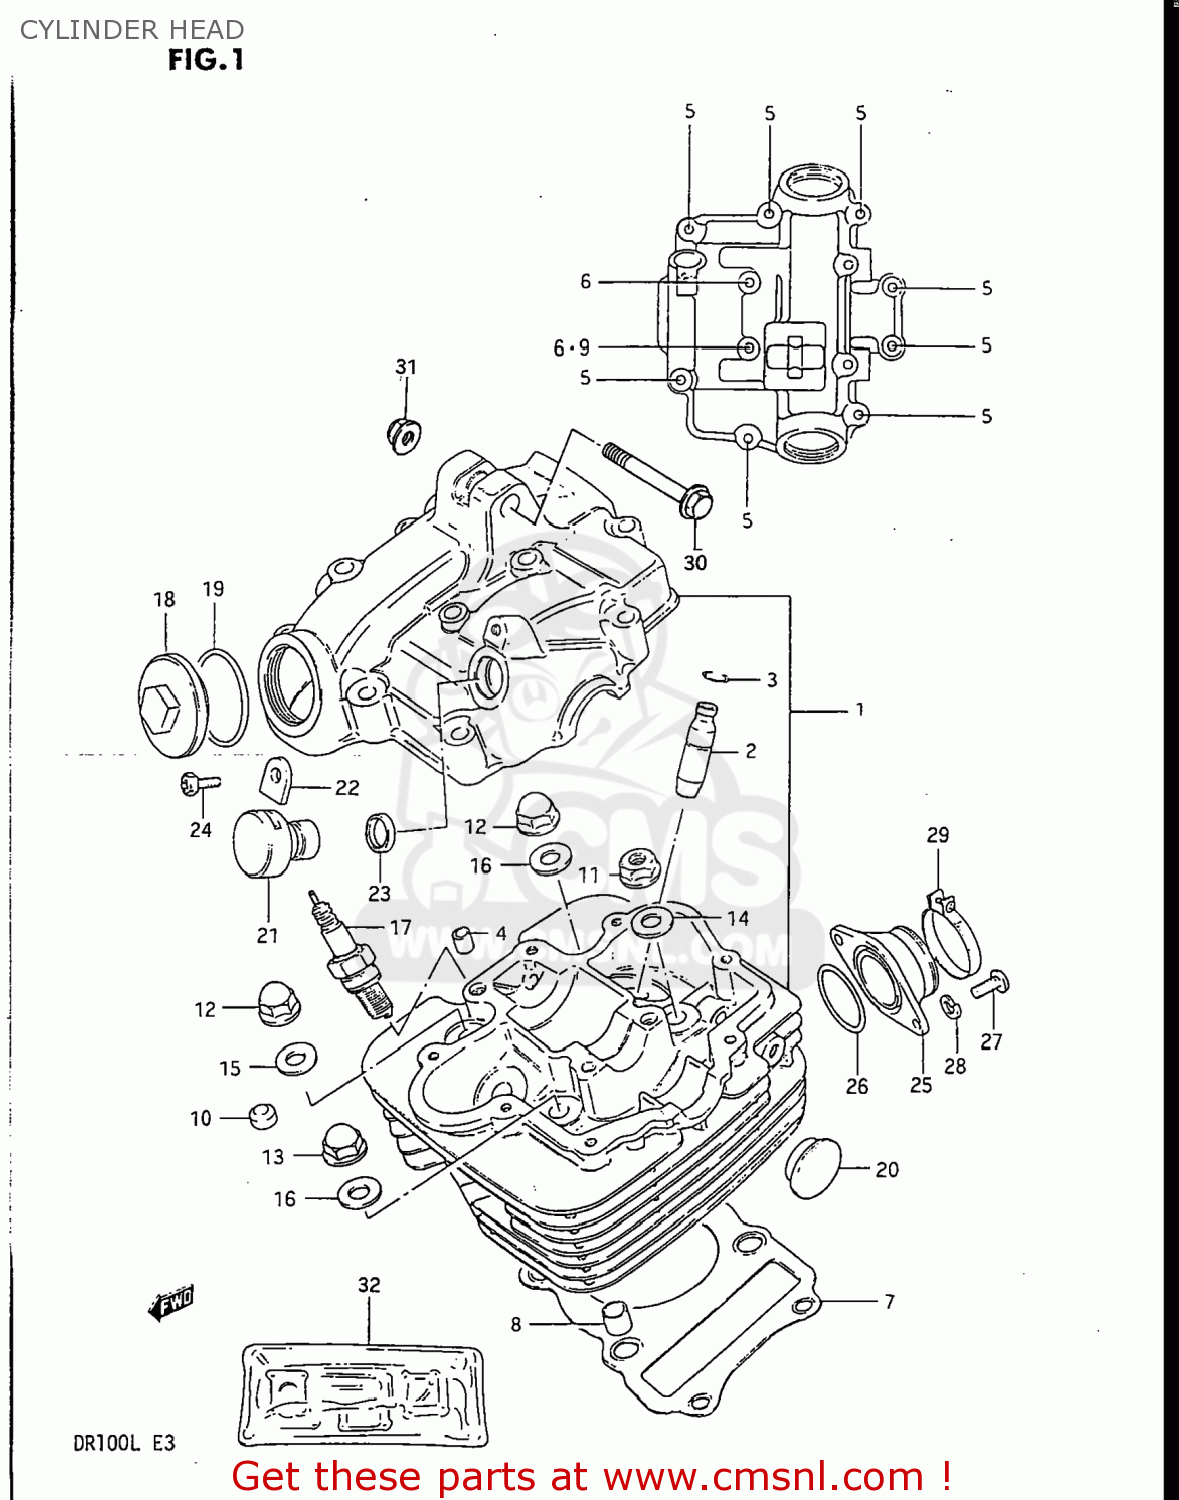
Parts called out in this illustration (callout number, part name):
1	HEAD ASSEMBLY,CYLINDER
2	GUIDE,VALVE
3	RING,SNAP
4	PIN(6.2X8X11)
5	BOLT 6X35
6	BOLT ,6X60
7	GASKET,CYLINDER HEAD
8	PIN
9	GASKET(5.8X13X1.2) (NAS)
10	PAD,CYLINDER HEAD
11	NUT
12	NUT (8MM)
13	NUT
14	WASHER(8.5X19X2.3)
15	WASHER (8.5X19X2.3)
16	GASKET (NAS)
17	SPARK PLUG D8EA
18	CAP,INSPECTION
19	O RING(D:3,ID:29.5)
20	PLUG(OD:22.5)
21	PLUG,TACH GEAR SLEEVE HOLE
22	PLATE,TACH DRIVE GEAR SLEEVE
23	SEAL,TACHOMETER DRIVEN
24	SCREW(5X12)
25	PIPE,INTAKE
26	O RING(D:2.4,ID:31.7)
27	SCREW
28	WASHER,LOCK
29	CLAMP
30	BOLT 8X50
31	NUT
32	GASKET SET
